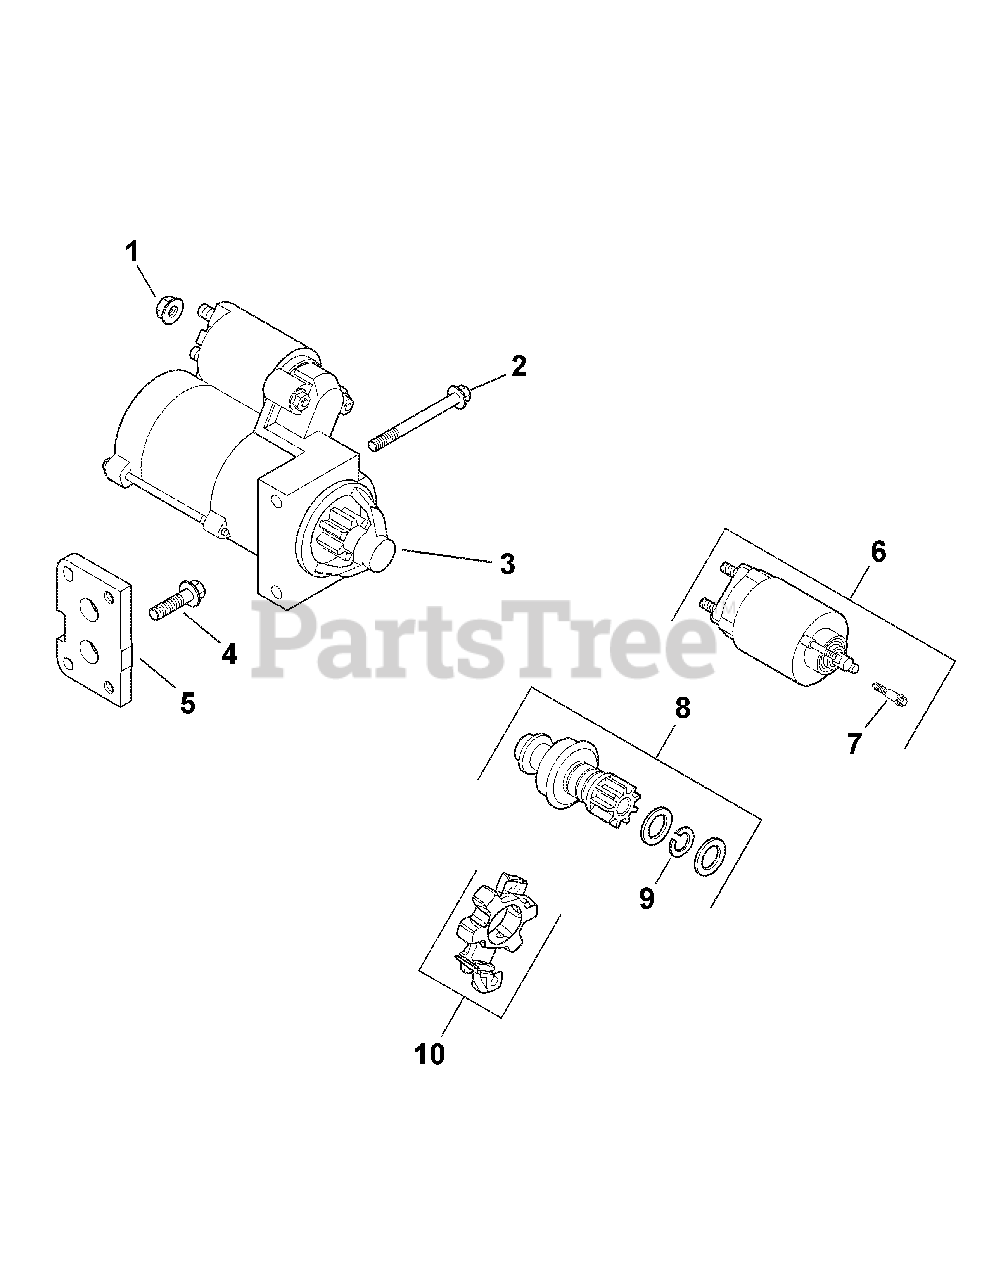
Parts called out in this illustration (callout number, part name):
1	Nut, Flg, M8 x 1.25
2	Screw, Flg, M8 x 1.25 x 80
3	Starter Ass’y, Solenoid Shift
4	Screw, Flg, M8 x 1.25 x 30
5	Plate, Starter
6	Kit, Solenoid
7	Screw, External Torx Head
8	Kit, Starter Pinion
10	Brush, Holder
